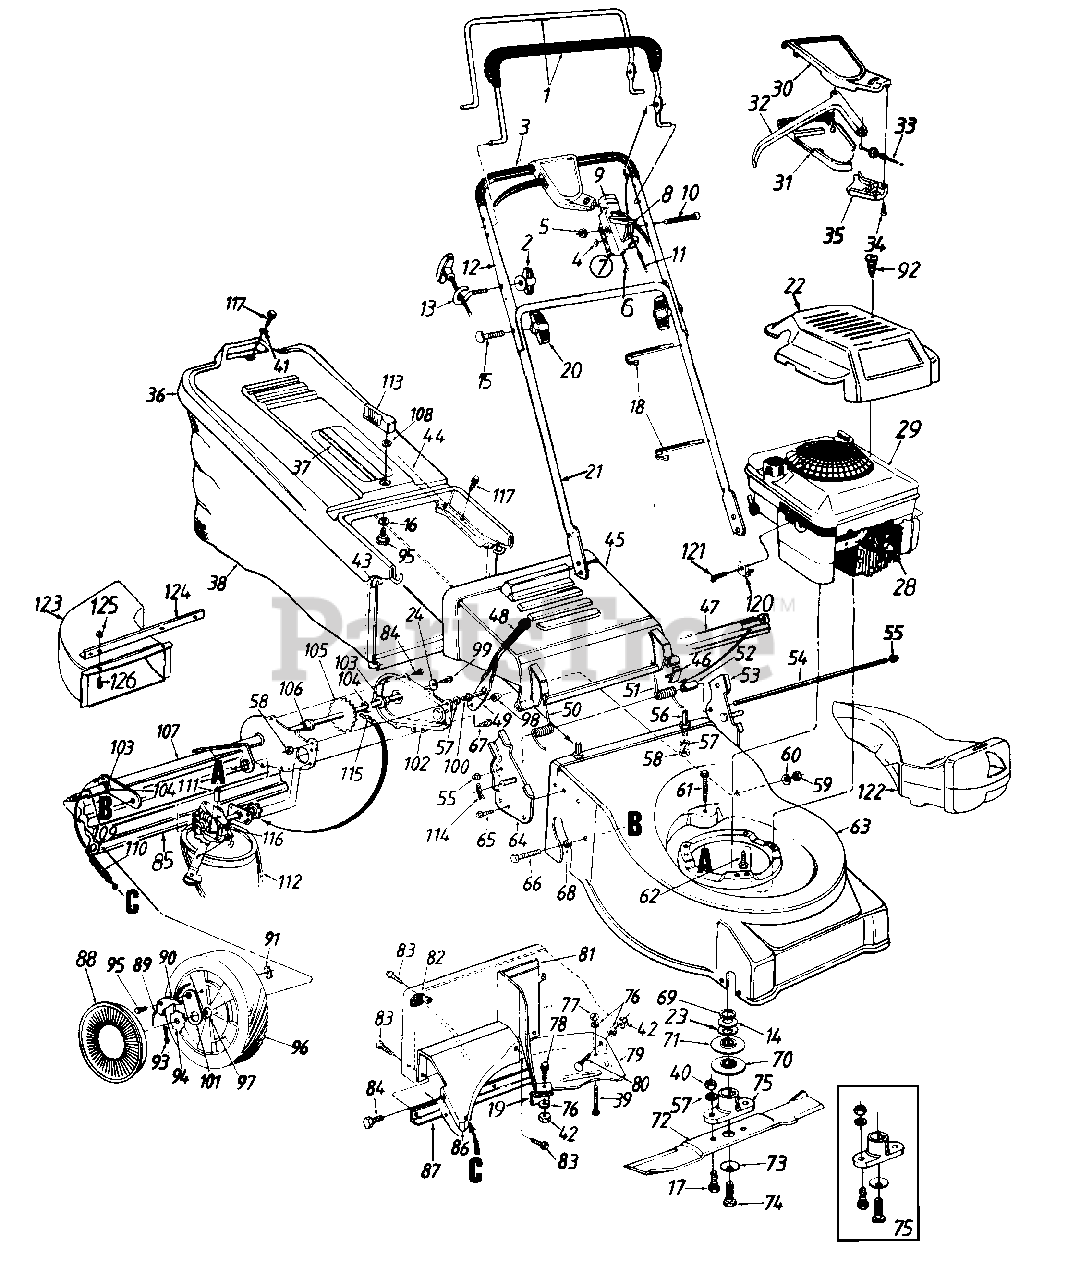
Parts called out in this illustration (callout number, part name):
2	Handle Knob 1/4-20 Thd.
3	Foam Grip
4	Spr. Wash. .66" I.D.
5	Hex L-Nut 1/4-20 Thd.
6	Throttle Cable-55" (B & S)
7	Throttle Box Comp.
8	Throttle Lever
9	Throttle Body
10	Oval C-Sunk Scr.
11	Control Cable-40.5" (B & S)
13	Rope Guide
14	Spr. Wash. .89" I.D.
15	Curved Hd. Bolt 5/16-18 x 2"
16	Bowed Washer
17	Hex Bolt 3/8-24 x 1" Lg.
18	Cable Tie
19	Stop Brkt.
20	Hand Knob
22	XTE Engine Shroud (Black)
23	FL-Wash. .88" I.D. x 1.85"
24	Bell-Wash. .265" I.D. x .75"
28	Spark Plug Boot
29	Engine
30	Control Cover Half-Upper
31	Control Cover Half-Lower
32	Control Lever
33	Drive Cable-51" Lg.
34	Flat C-Sunk Hd. Tap Scr. #10 x .75" Lg.
35	Cable Mtg. Cap
36	Hardtop Bag Cover
37	Hardtop Handle
38	Grass Bag
39	Truss Mach. Scr. 1/4-20 x 1.0" Lg.
40	Hex Nut 3/8-24 Thd.
41	FL-Wash. .281" I.D. x 62"
42	Hex Nut 1/4-20 Thd.
44	Rear Chtcher Frame
45	Chute Deflector
46	Deflector Plug
47	Seal-Extrusion
49	Spring Lever
50	Torsion Spring-R.H.
51	Torsion Spring-L.H.
52	Spacer .255" I.D.
55	Cap Speed Nut
56	Shld. Pin 3/8-24 x 1.43" Lg.
57	L-Wash. 3/8" I.D.
58	Hex Jam Nut 3/8-24 Thd.
59	Hex L-Nut 3/8-24 Thd.
60	Bell-Wash. .38" I.D. x .88"
61	Hex Wash. Hd. Tap Scr. 1/4-20 x 1.5" Lg.
62	Hex L-Wash. Hd. Scr. 3/8-16 x 1" Lg.
63	21" Deck Ass'y.
66	Hex Wash. Hd. Tap Scr. 3/8-16 x .75" Lg.
67	Hex Wash. Hd. Tap Scr. 1/4-20 x .5" Lg.
68	Spacer .383" I.D.
69	Crankshaft Spacer
70	Pulley Half-Lower
71	Pulley half-Upper
72	21" Blade
73	Bell-Wash. .39" I.D.
74	Hex Bolt 3/8-24 x 1.5" Lg.
75	Blade Adapter Kit
76	L-Wash. 1/4" I.D.
77	Hex Jam Nut 1/4-20 Thd.
78	Hex Bolt 1/4-20 x .85" Lg.
79	Ext. Baffle
80	Carr. Bolt 1/4-20 x .50" Lg.
83	Torx Mach. AB-Tap Scr. 1/4 x 62" Lg.
84	Hex B-Tap Scr. 1/4 x .38" Lg.
85	Rear Flap
88	Hub Cap
89	Plastic Spring
90	Pawl .345" I.D.
91	Weld Top L-Nut 1/4-20 Thd.
92	Hi-Lo Scr. #10 x 1.25" Lg.
93	Cotter Pin 1/8" Dia.
94	Ratchet Wheel 1.62" O.D.
95	Shld. Bolt .342" Dia. x .268"
96	Wheel Ass'y. Comp.-Rear
97	Bearing 1/2" I.D.
98	Shld. Spacer .50" Dia.
99	Hex Bolt 1/4-20 x .62" Lg. (Gr. 5)
100	Shld. Pin 3/8-24 x 1.43" Lg.
101	Pawl Plate
104	FL-Wash. .531" I.D. x .93"
105	Rear Axle Ass'y.
106	Hex Flange Bearing
109	Spacer .513" I.D.
110	Extension Spring 3.8" Lg.
111	Spacer .325" I.D.
112	V-Belt
113	Grass Catcher Locking Knob
114	Internal Cotter Pin 5/16" Dia.
115	#48 Chain .50" Pitch x 30 Links
116	Transmission Comp.
117	Hex L-Wash. H.D. AB-Tap Scr. 1/4 x .62" Lg.
120	Cable Clamp (B & S)
121	Hex Self-Tap Scr. #10-32 x .62" Lg. (B & S)
122	Mulching Plug
123	Chute Deflector
125	Hex L-Nut 1/4-20 Thd.
126	Mach. Scr. 1/4-20 x .5" Lg.
